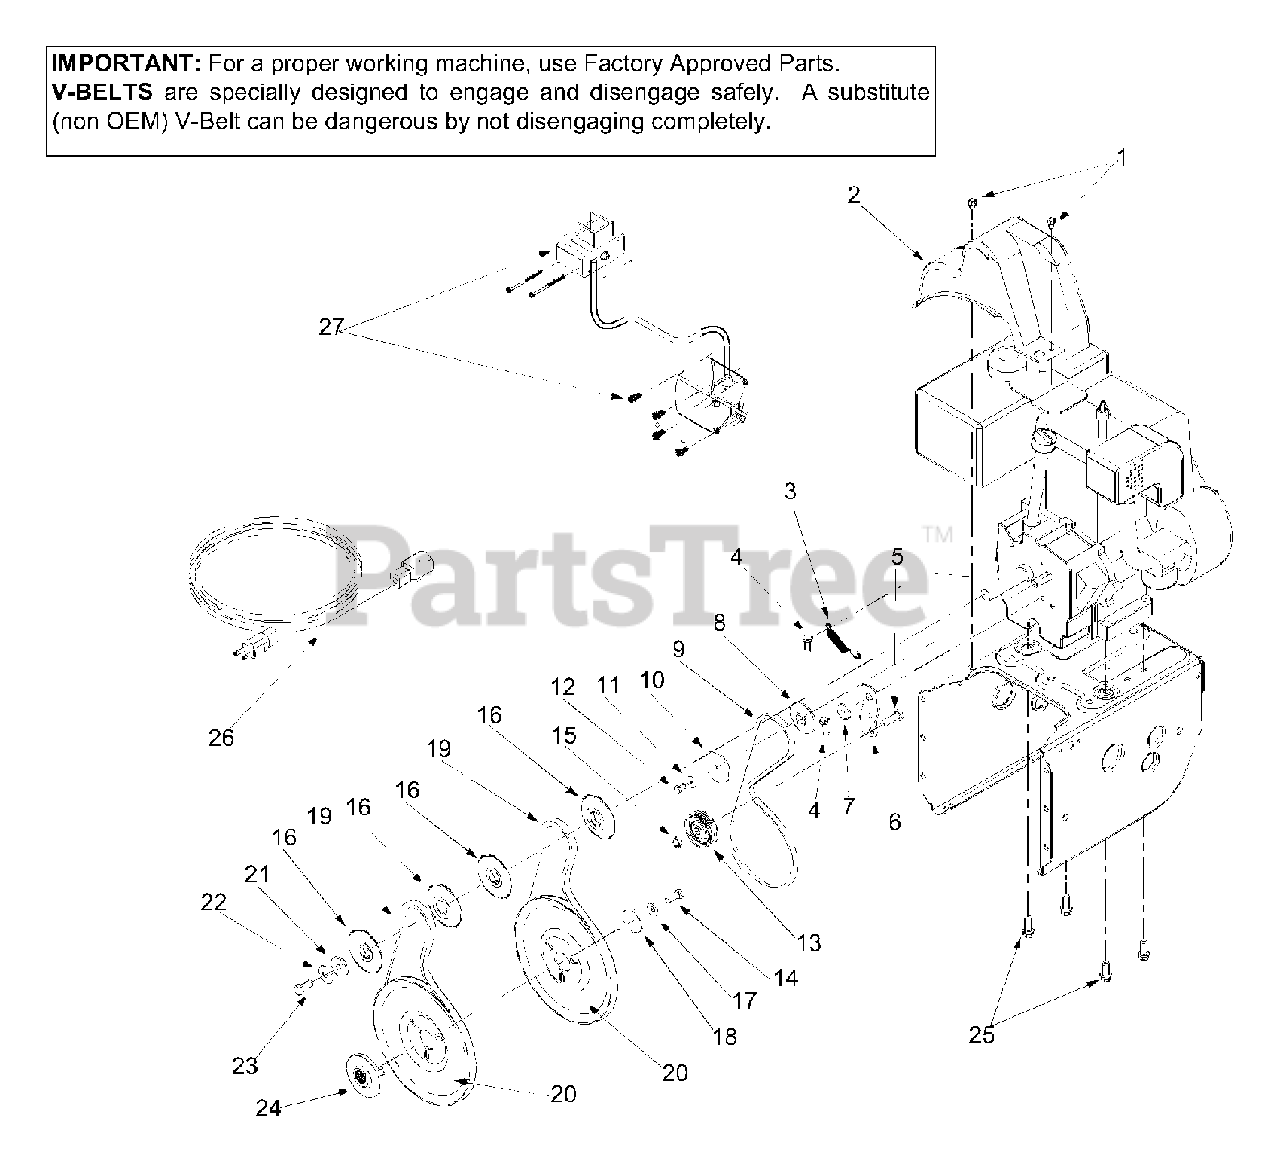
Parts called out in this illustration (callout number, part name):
1	Hex Washer Screw 1/4-20 x .625
2	Belt Cover
3	Extension Spring
4	Hex Screw 5/16-24 x .75
5	Hex Cap Screw 3/8-16 x 1.25
8	Pulley Half
9	V-Belt
10	Pulley Half
11	Bell Washer
12	Hex Cap Screw 1/4-28 x .50
13	Flat Idler
14	Lock Hex Cap Screw 5/16-24
15	Lock Jam Nut 3/8-16
16	Pulley Half
17	Bell Washer
18	Flat Washer
19	Belt
20	Auger Pulley
21	Flat Washer 3/8 x 1.25 OD
22	Bell Washer
23	Hex Cap Screw 3/8-24
24	Adapter Pulley
25	Hex Screw 3/8-16 x 1.0
26	Extension Cord
27	Electric Start
